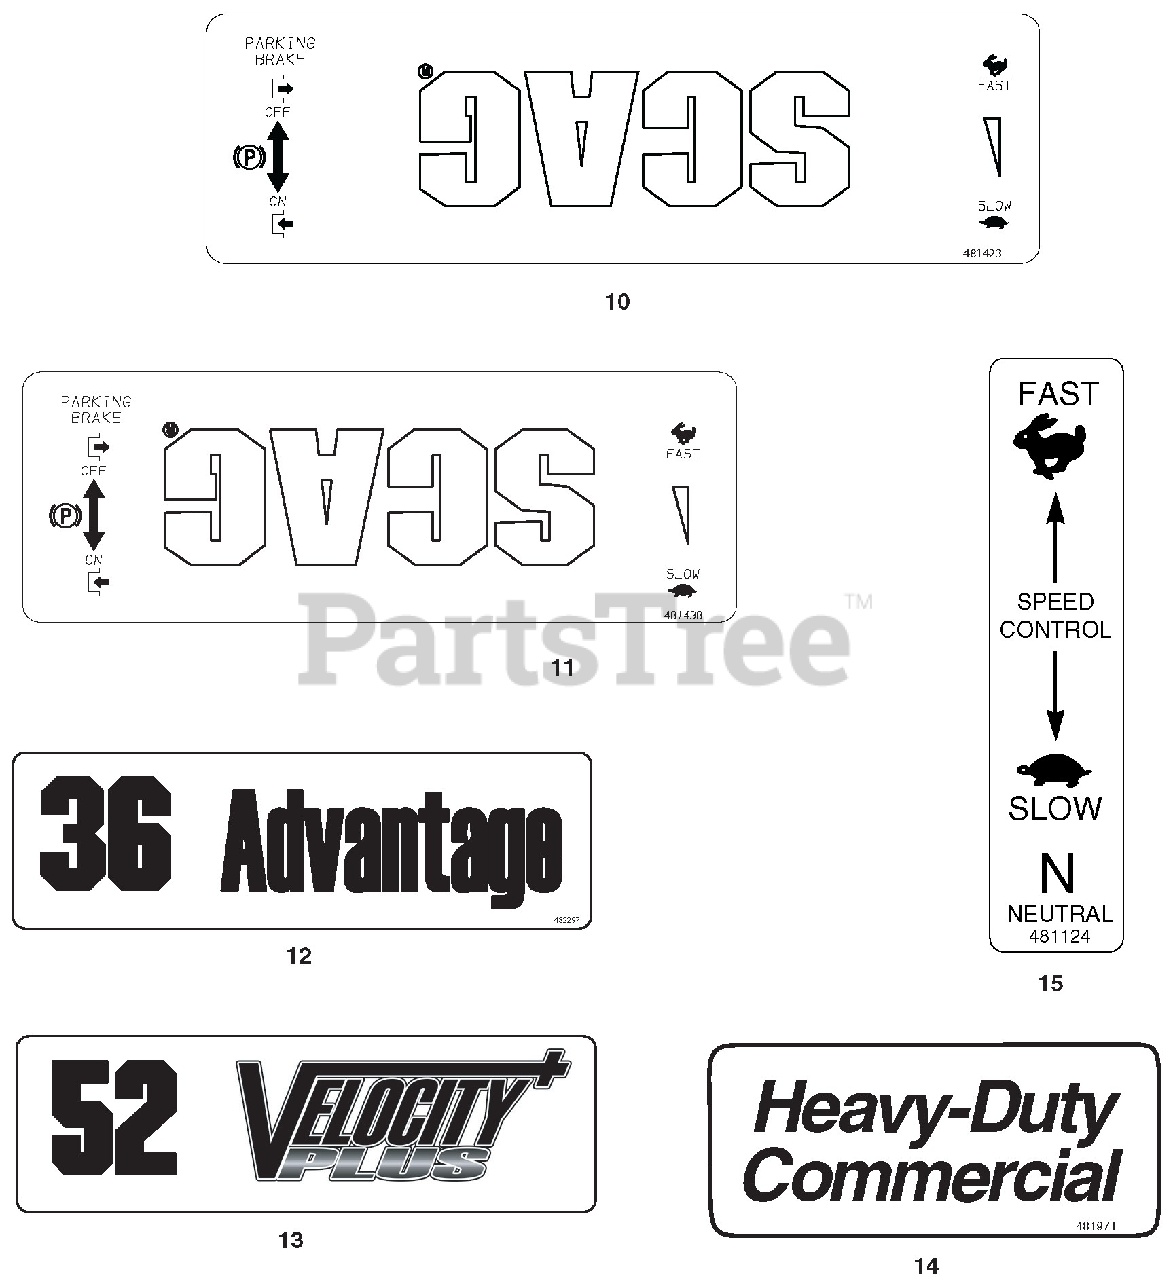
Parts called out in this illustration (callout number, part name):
10	Decal, Instrument Panel - Front
11	Decal, Instrument Panel - Front
12	Decal, 36 Advantage
13	Decal, 48 Velocity Plus
13	Decal, 52 Velocity Plus
13	Decal, 61 Velocity Plis
14	Decal, Heavy Duty Commercial
15	Decal, Speed Control
